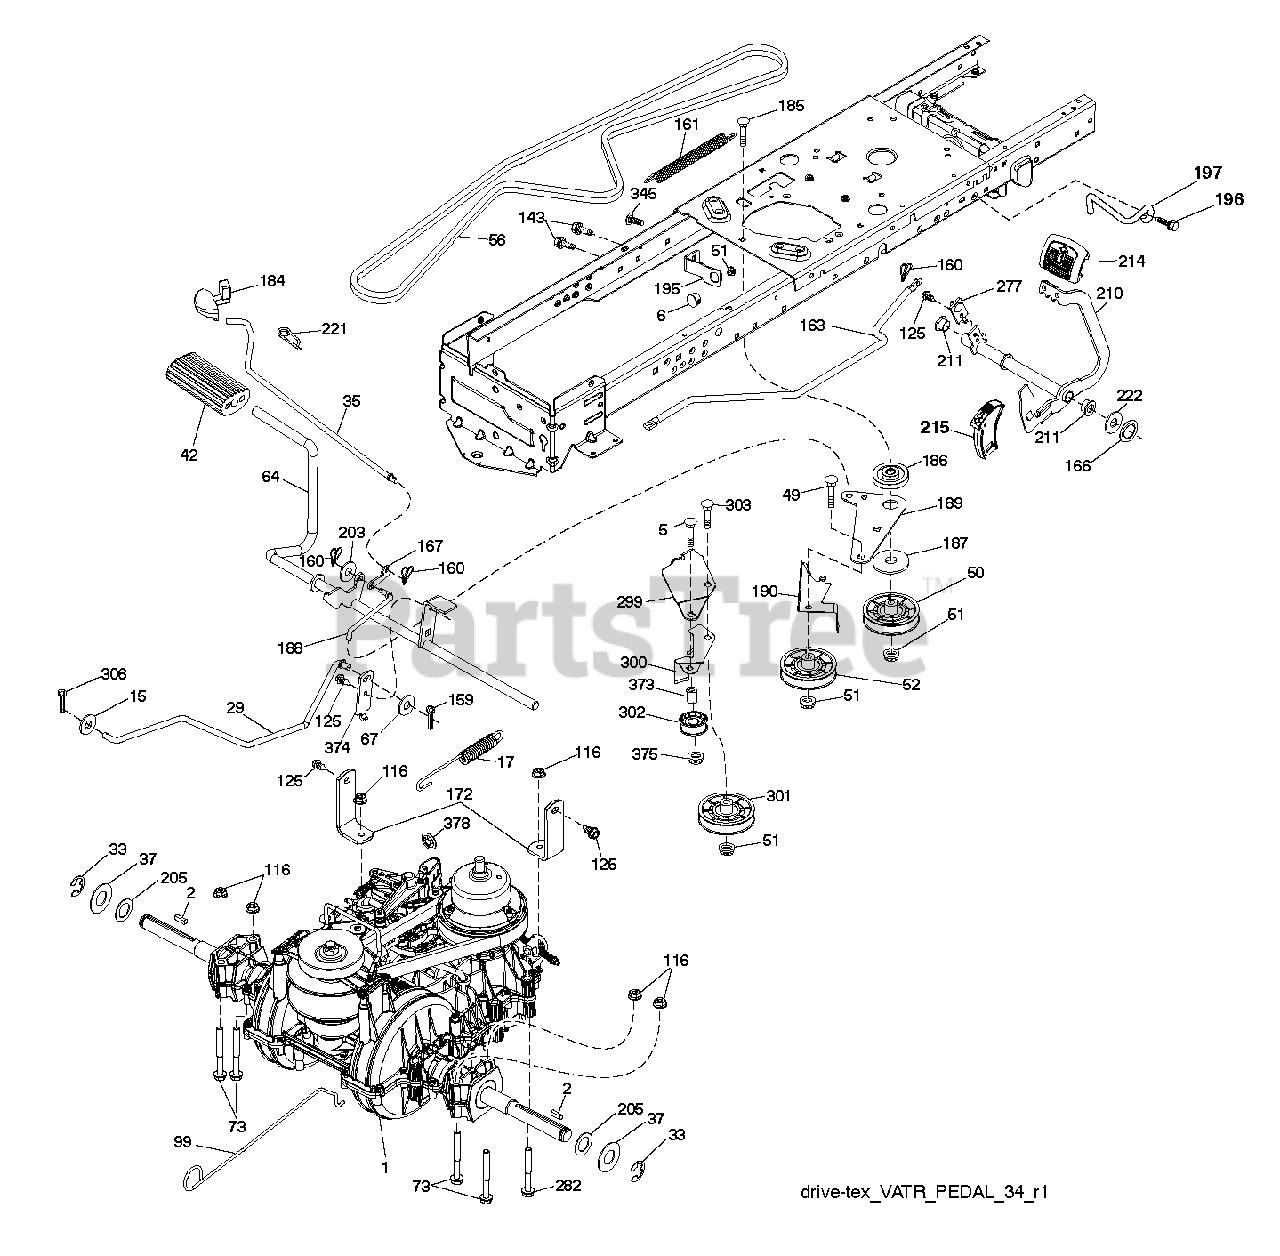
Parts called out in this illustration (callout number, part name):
2	SQUARE KEY
6	GROMMET T
17	Brake Variator Spring
29	RB ROD.BRAKE.VARIATOR.SD2
33	E-RING LT
35	ROD .BRAKE. PARKING. GT. HUSQ.
37	WASHER.HARDENED
49	BOLT
50	IDLER.FLAT.910.OFFSET
51	NUT LOCK FLG 3/8-16 UNC
52	IDLER.V-GROOVE.910.OFFSET
56	BELT.DRIVE.MOWER.TEX.42"
64	SUBASM.SHAFT.PEDAL.BRAKE
67	WASHER
73	BOLT HEX 5/16-18 GR 5
99	ROD.BYPASS.VARIATOR.GEN2
116	NUT LOCK HEX FLANGE 5/16-18
125	SCREW
143	SCREW LT
159	COTTER PIN
160	RETAINER CLIP
161	SPRING, RETURN LT
163	ROD.CONTROL.PEDAL.VARIATOR
166	NUT.PUSH.625
167	LATCH.BRAKE.SPRING
172	STRAP.TORQUE.VARIATOR
186	SPACER.RETAINER
187	WASHER 12/32X2X10GA
188	LINK.CLUTCH.GROUND.DRIVE
189	BELLCRANK.GROUND.DRIVE.TEX.
190	KEEPER.BELLCRANK.DRIVE
195	BRACKET.BRAKE.BRAKE.VAR.SD
196	SCREW 3/8-16X1
197	Clutch Anti-Rotation Wireform
203	WASHER
210	WELDMENT.PEDAL.VARIATOR
211	BEARING.NYLON
214	PEDAL.FORWARD.PAD.TEX
215	CAP.PEDAL.REVERSE.VARIATOR
221	RETAINER.SPRING.CLIP.H
222	WASHER 21/32 X 1-1/4 X 10 GA.
277	SUBASM.LINK.ROCKER.PEDAL
282	BOLT HEX FLGHD 5/16-18X3 GR. 5
299	BRACKET.MOUNT.IDLERS
300	KEEPER.IDLERS.REAR.VARIATOR
301	PULLEY.IDLER.V-GROOVE
302	PULLEY.IDLER.FLAT.2"
303	BOLT CARRIAGE
306	PIN COTTER
373	SPACER.IDLER
374	ARM.CONTROL.BRAKE
375	LOCKNUT
378	NUT.PUSH.8MM
